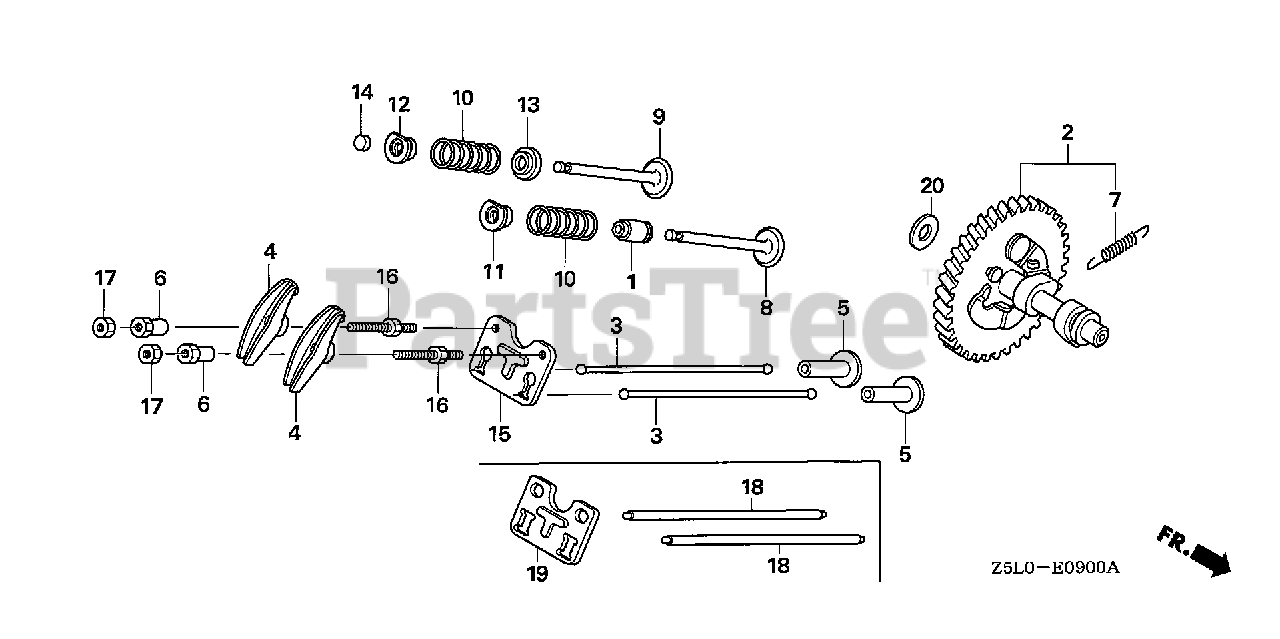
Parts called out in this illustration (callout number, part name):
1	SEAL, VALVE STEM
2	CAMSHAFT (STD) (PRESS FIT CAM)
3	ROD, PUSH
4	ARM, VALVE ROCKER
5	LIFTER, VALVE
6	PIVOT, ROCKER ARM
7	SPRING, WEIGHT RETURN
8	VALVE, IN.
9	VALVE, EX.
10	SPRING, VALVE
11	RETAINER, IN. VALVE SPRING (EXHAUST SIDE)
12	RETAINER, IN. VALVE SPRING (EXHAUST SIDE)
13	SEAT, VALVE SPRING
15	PLATE, PUSH ROD GUIDE
16	BOLT, PIVOT (8MM)
17	NUT, PIVOT ADJ.
